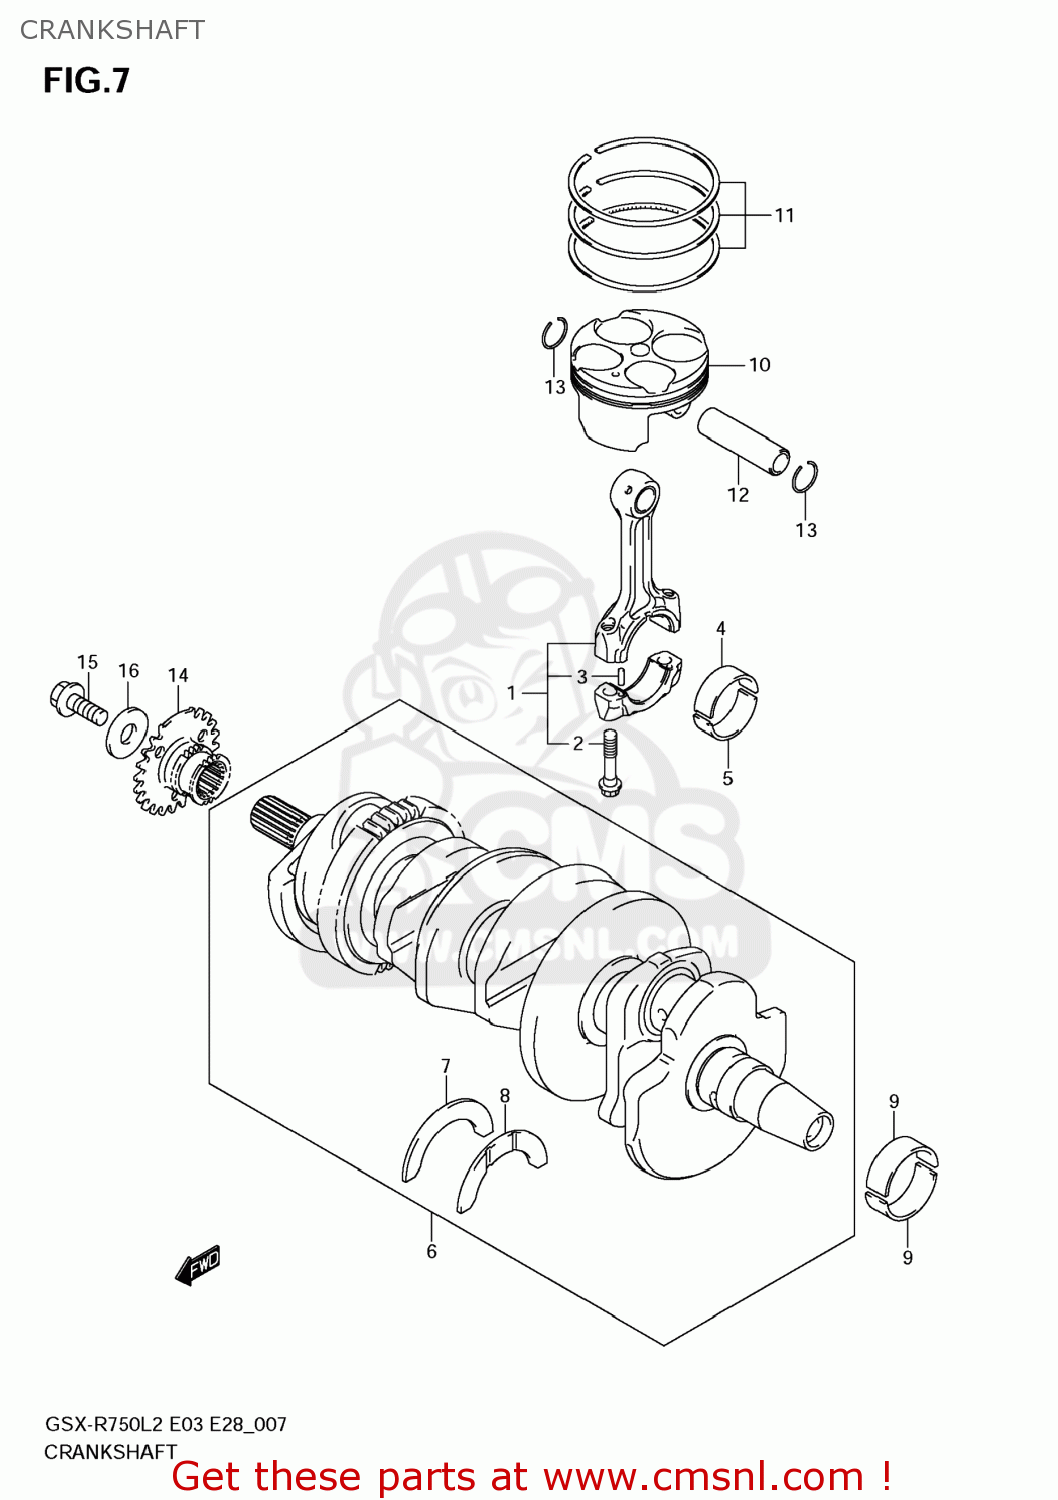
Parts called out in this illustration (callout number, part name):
1	CONNECTING ROD ASSY
2	BOLT,CONNECTING ROD
3	PIN
4	BEARING,CRANK PIN
5	BEARING,CRANK PIN GREEN
6	CRANKSHAFT SET
7	BEARING,CRANK THRUST(GREEN)
8	BEARING,CRANK THRUST(RED)
9	BEARING,CRANKSHAFT
10	PISTON
11	RING SET,PISTON
12	PIN,PISTON
13	CIRCLIP
14	SPROCKET,CAM CHAIN DRIVE
15	BOLT(10X23)
16	WASHER
